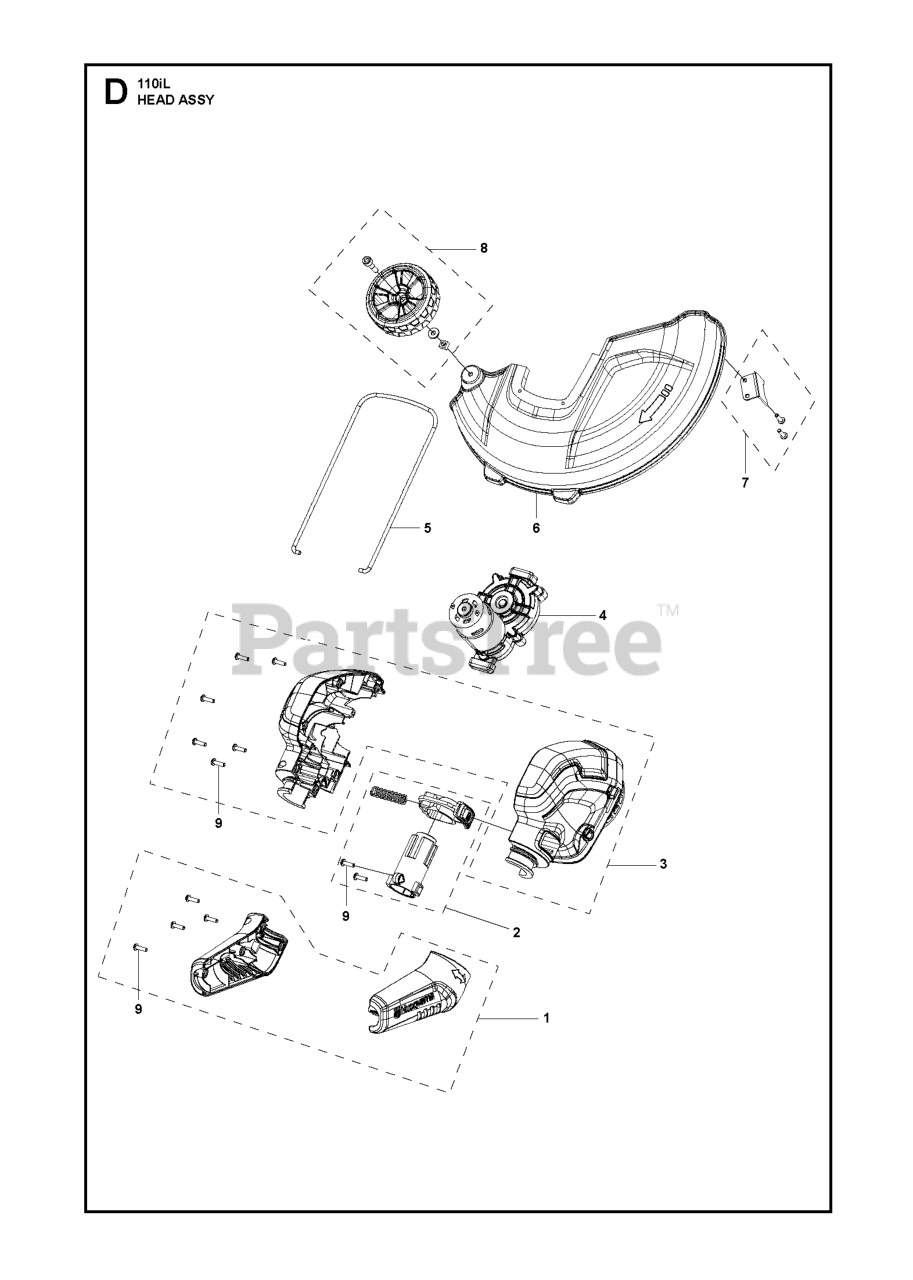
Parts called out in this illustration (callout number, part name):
1	WHEEL.STEERING.PREM.2.
2	NUT.LOCK.5/16-18
3	BOLT.CARRIAGE.5/16-18
4	PULLEY, IMPELLER
5	BEARING FLANGE
6	NUT, HEX FLANGE 5/16-18
7	BOLT.CARRIAGE.5/16-18X
8	BOLT
10	HOUSING, AUGER
11	BAR, SCRAPER
12	BRACKET, CORNER DISCHARGE
13	BASE DISCHARGE CHUTE
14	WASHER, FLAT
15	WASHER, LOCK 5/16
16	Screw, Hex Head 5/16-18 x 3/4
17	GREASE FITTING
18	SCREW, HEX HD 5/16X1
19	LOCKNUT.NYLOC.1/4-20
20	NUT, HEX FLANGE 5/16-18
22	SKID PLATE RH
25	BOLT
26	BEARING.BALL.AUGER.SHAFT
27	WASHER TRUST 1"
28	BOLT, SHEAR
29	SKID PLATE LH
30	RP AUGER ASSEMBLY, RH
31	RP AUGER ASSEMBLY, LH
33	BUSHING, FLANGE 3/4
34	WASHER, THRUST 3/4
35	BEARING TRUST 3/4 NTA-1220
36	SHAFT, IMPELLER
37	WASHER, THRUST 5/8
38	FLANGE BUSHING-5/8
39	HEX SCREW-5/16 X 3/4
40	CASE PLUG
41	GEARBOX HOUSING-RH
42	OIL SEAL
43	FLANGE BUSHING-1"
44	KEY, SQUARE 1/4 X .875
45	WORM GEAR
46	AUGER SHAFT
47	HOUSING.GEARBOX.LH(SERVICE)
48	IMPELLER ASSY
49	SCREW.HEX.HD1/4-20X
50	GEARBOX GASKET
51	PIN, ROLL 3/16 X 1-1/8
55	SPACER.3943.SLEEVE.250X.47
56	RP WRENCH, SNOWTHROWER
57	GEARBOX.ASSEMBLY.AUGER
58	BEARING RETAINER, PLASTIC
